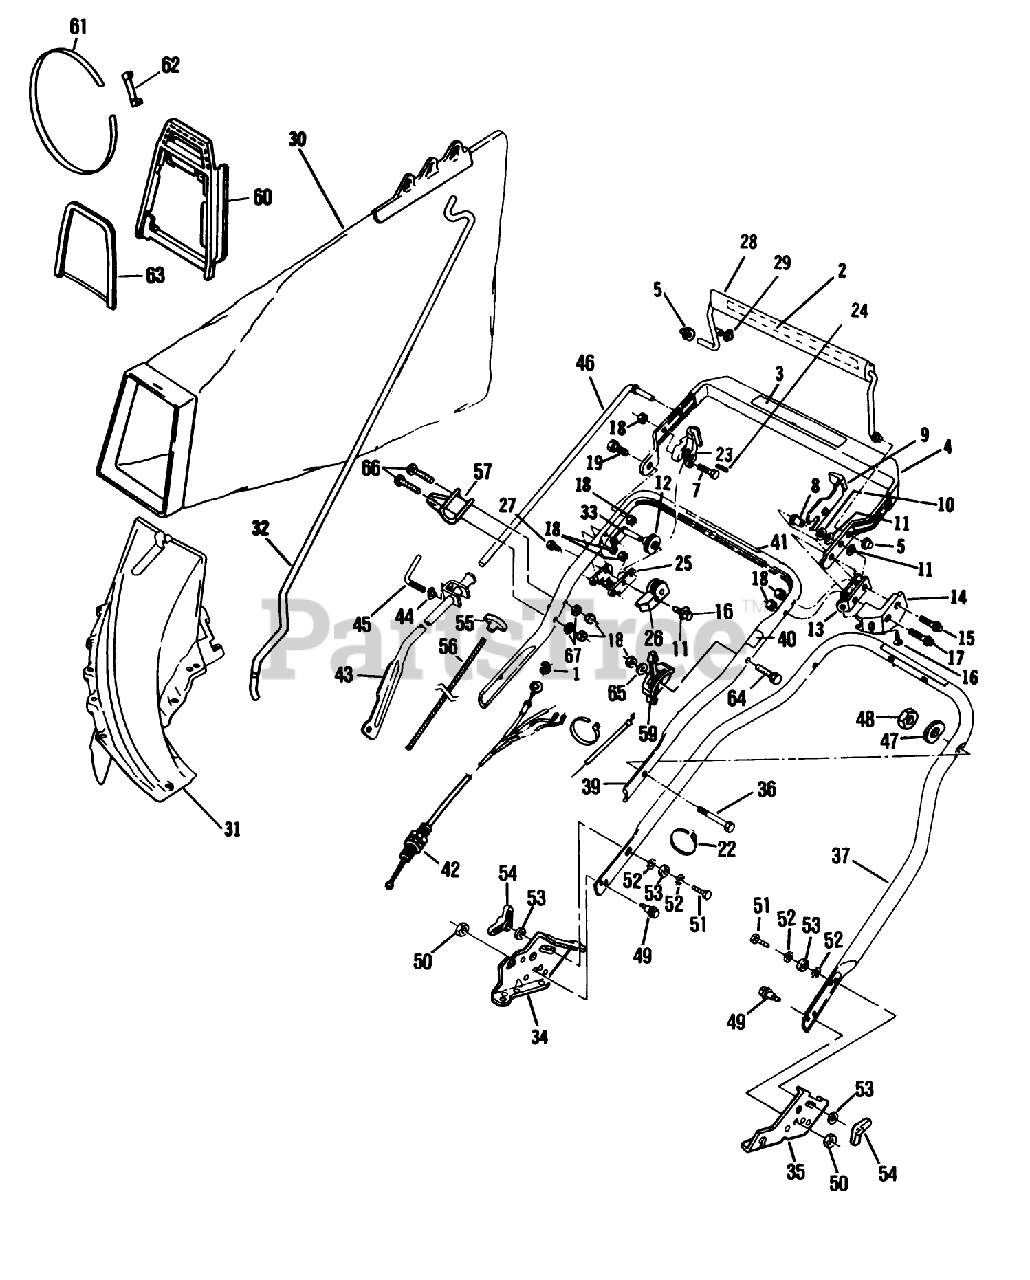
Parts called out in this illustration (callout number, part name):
1	RET. RING
6	SCREW-HH
8	SPACER
10	WASHER M
12	PULLEY PL
13	DOWN STOP
14	LOCKOUT GUARD
15	BOLT SHOU
16	SCREW F
17	SCREW
18	LOCKNUT E
19	BOLT
23	CAM HOFFER
29	NUT ACORN
30	Grass Bag
31	CHUTE ASSY
32	ROD GRASSBAG
42	CONTROL CABLE
46	CONTROL ROD
47	WASHER-CURVED
48	NUT-LOCK F
49	BOLT
50	NUT-JAM, LOCKING
52	LOCK WASHER LARSON
53	WASHER
54	NUT-WING
55	HANDLE START UM&D
58	WASHER-FLAT
60	CHUTE - ADAPTER
63	CHUTE BRACE
65	WASHER-FLAT
67	WASHER
